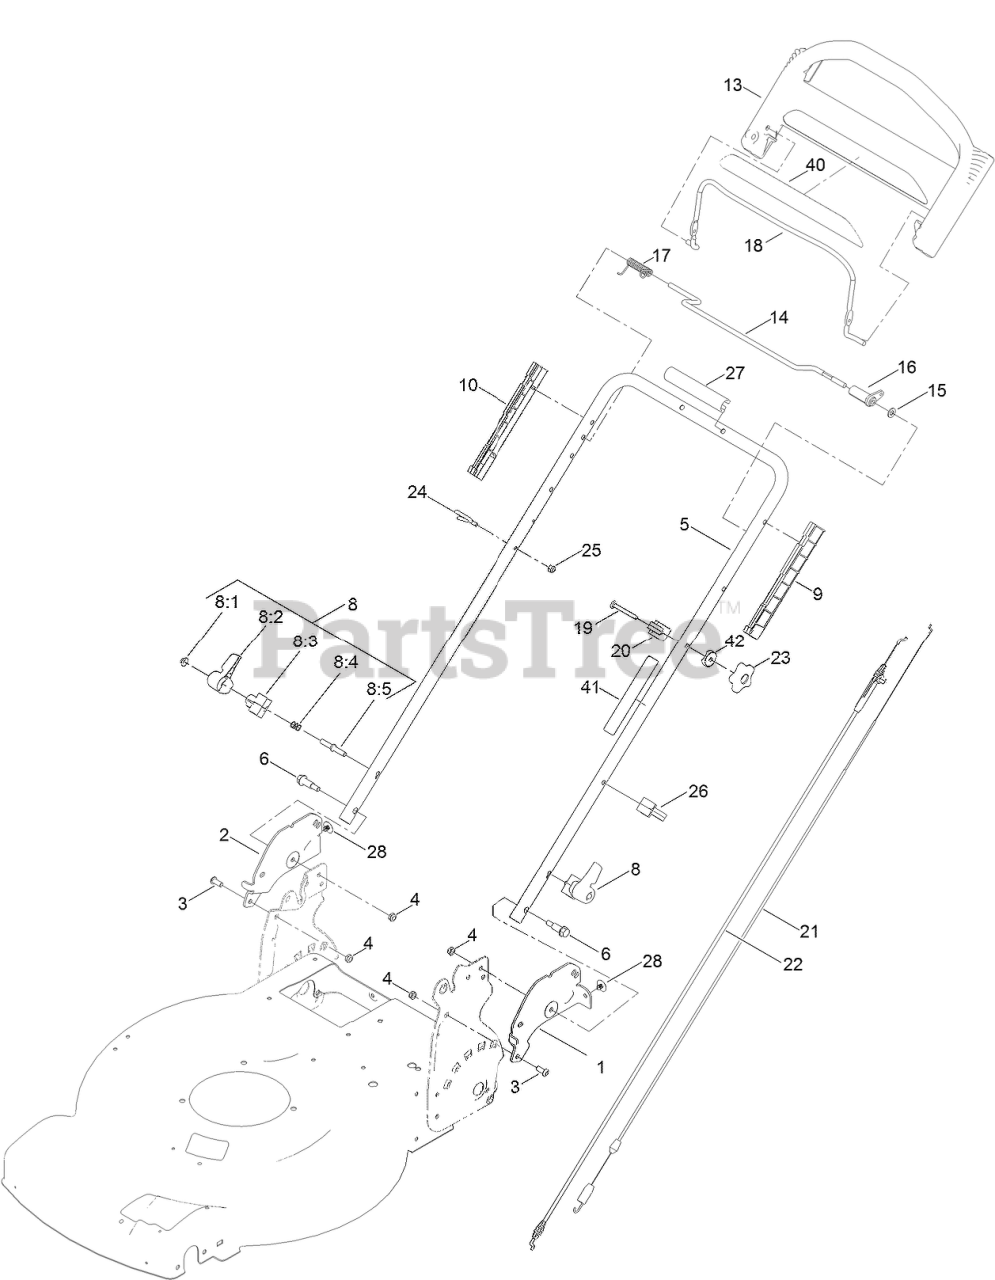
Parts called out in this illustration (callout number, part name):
1	PLATE-HANDLE, LH
2	PLATE-HANDLE, RH
3	SCREW-HSBH
4	NUT-LOCK, NI
6	BOLT-SHOULDER
8	QUICK RELEASE ASM
8:2	LEVER
8:3	ANCHOR-SPRING
8:4	SPRING-COMPRESSION
8:5	ROD-RELEASE
9	GUIDE-LH
10	GUIDE-RH
13	HANDLE-CONTROL
14	BAR-CONTROL, TRACTION
15	WASHER-PLAIN
16	LEVER-TRACTION
18	BAIL-BRAKE
19	SCREW-CARR
20	ANCHOR-CABLE
21	CABLE-TRACTION
22	CABLE-BRAKE
23	KNOB-HANDLE, LOCKING
24	GUIDE-ROPE
25	NUT-LOCK, NI
26	GUIDE-CABLE
27	HANDLE-COVER
28	CLIP-TREE
41	DECAL-TRACTION, ADJUST
42	WASHER-CURVED
